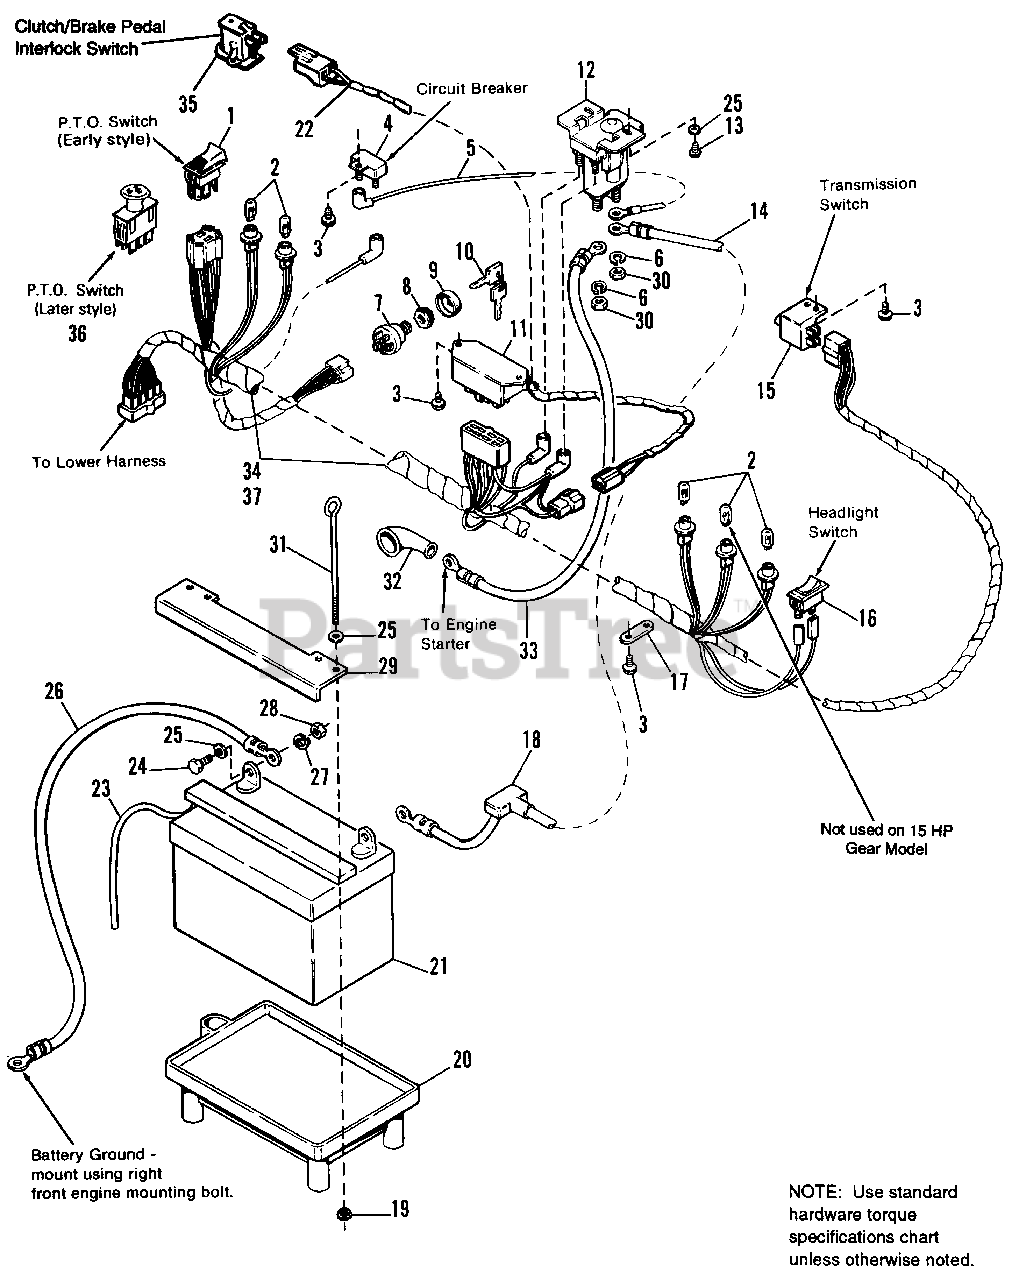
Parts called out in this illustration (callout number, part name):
1	SWITCH, PTO, Electric Clutch (Early style)
2	BULB, Indicator Light
3	SCREW, Plastite, #8-16 x 1/2
4	CIRCUIT BREAKER
6	LOCKWASHER, 5/16
7	SWITCH, Ignition
8	ADAPTER, Nut
9	COVER, Key Switch
12	SOLENOID
13	SCREW, Plastite, 1/4-20 x 5/8
14	CABLE, Battery to Solenoid
15	SWITCH, Transmission, Neutral Start
16	SWITCH, Headlight
17	STRAP, Wire Retainer
18	BOOT, Insulator
19	NUT, Plastic, 1/4-20
20	TRAY, Battery
23	HOSE, Battery, Drain
24	CAPSCREW, Hex, 1/4-20 x 3/4
25	WASHER, Plain, 9/32
26	CABLE, Battery to Ground
27	LOCKWASHER, 1/4
28	NUT, Hex, Full, 1/4-20
29	HOLD DOWN, Battery
30	NUT, Hex, 5/16-24
31	ROD, Battery Hold Down
32	COVER, Terminal
33	CABLE, Solenoid to Starter
34	HARNESS, Upper (Early style w/six-way PTO switch connector)
35	SWITCH, Interlock, Clutch/Brake Pedal
36	SWITCH, PTO Electric Clutch (Later style)
37	HARNESS, Upper (Later style w/8-way PTO switch connector)
